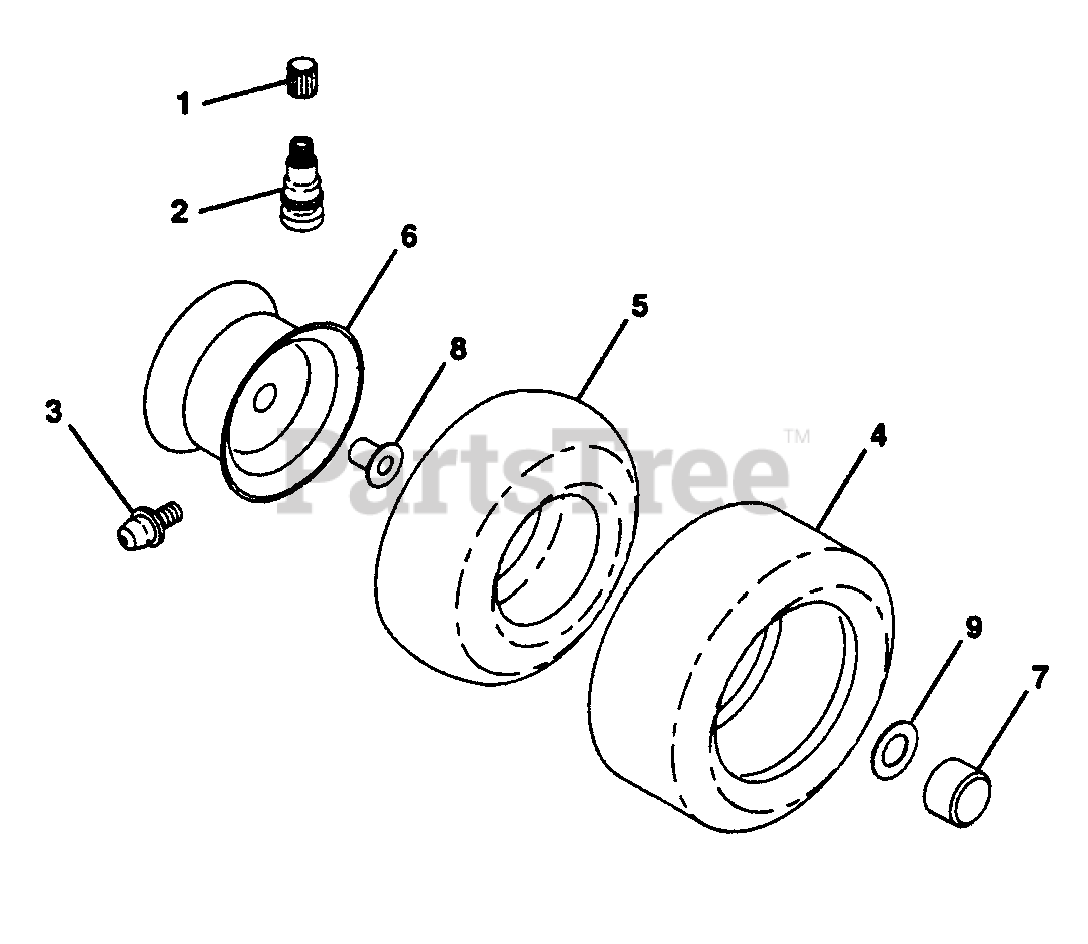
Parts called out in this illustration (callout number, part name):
1	Cap, Valve Stem
2	Stem, Valve
3	Fitting, Grease
4	Tire, Front
4	Tire, Rear
5	Tube, Front Tire
5	Tube, Rear Tire
6	Rim, Front
7	Cap, Hub Axle
8	Bearing Flange
9	Washer 25/32 x 1-5/8 x 16 Gauge
